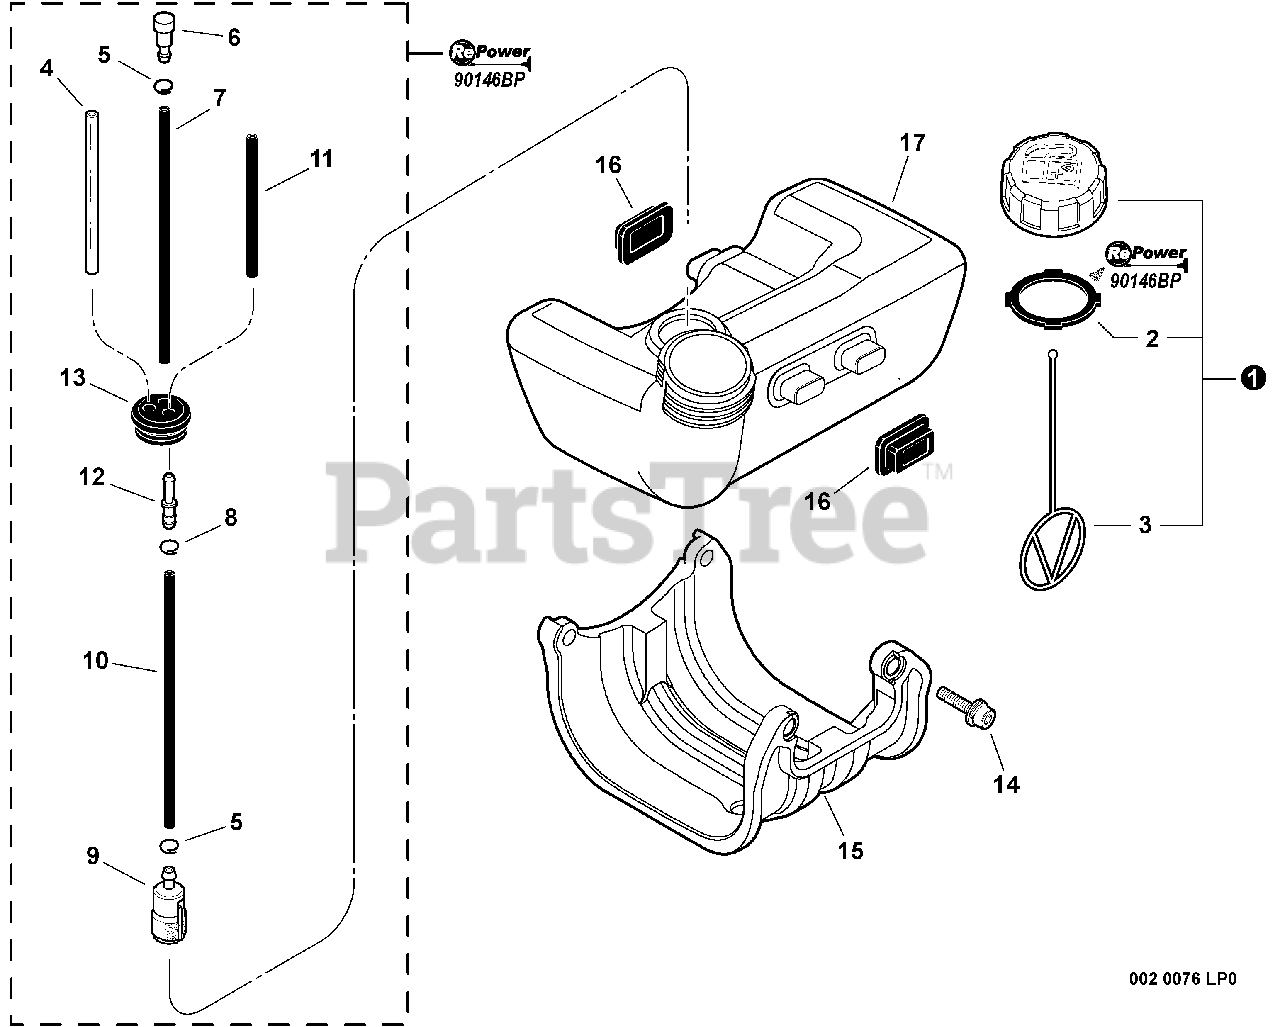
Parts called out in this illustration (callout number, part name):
1	CAP ASSY - RED
2	GASKET, CAP
3	CONNECTOR, CAP
4	PIPE - 3X6X80 -- CLEAR
5	CLIP - 6
6	VENT, FUEL TANK
7	PIPE - 3X6X90 -- BLACK
8	CLIP - 6.5
9	FILTER, FUEL
10	PIPE - 3X6X120 -- BLACK
11	PIPE - 3X5X67 -- BLACK
12	CONNECTOR, PIPE
13	GROMMET
14	SCREW - 5X20
15	GUARD, FUEL TANK
16	CUSHION, FUEL TANK
17	TANK, FUEL
18	RePower FUEL SYSTEM KIT
